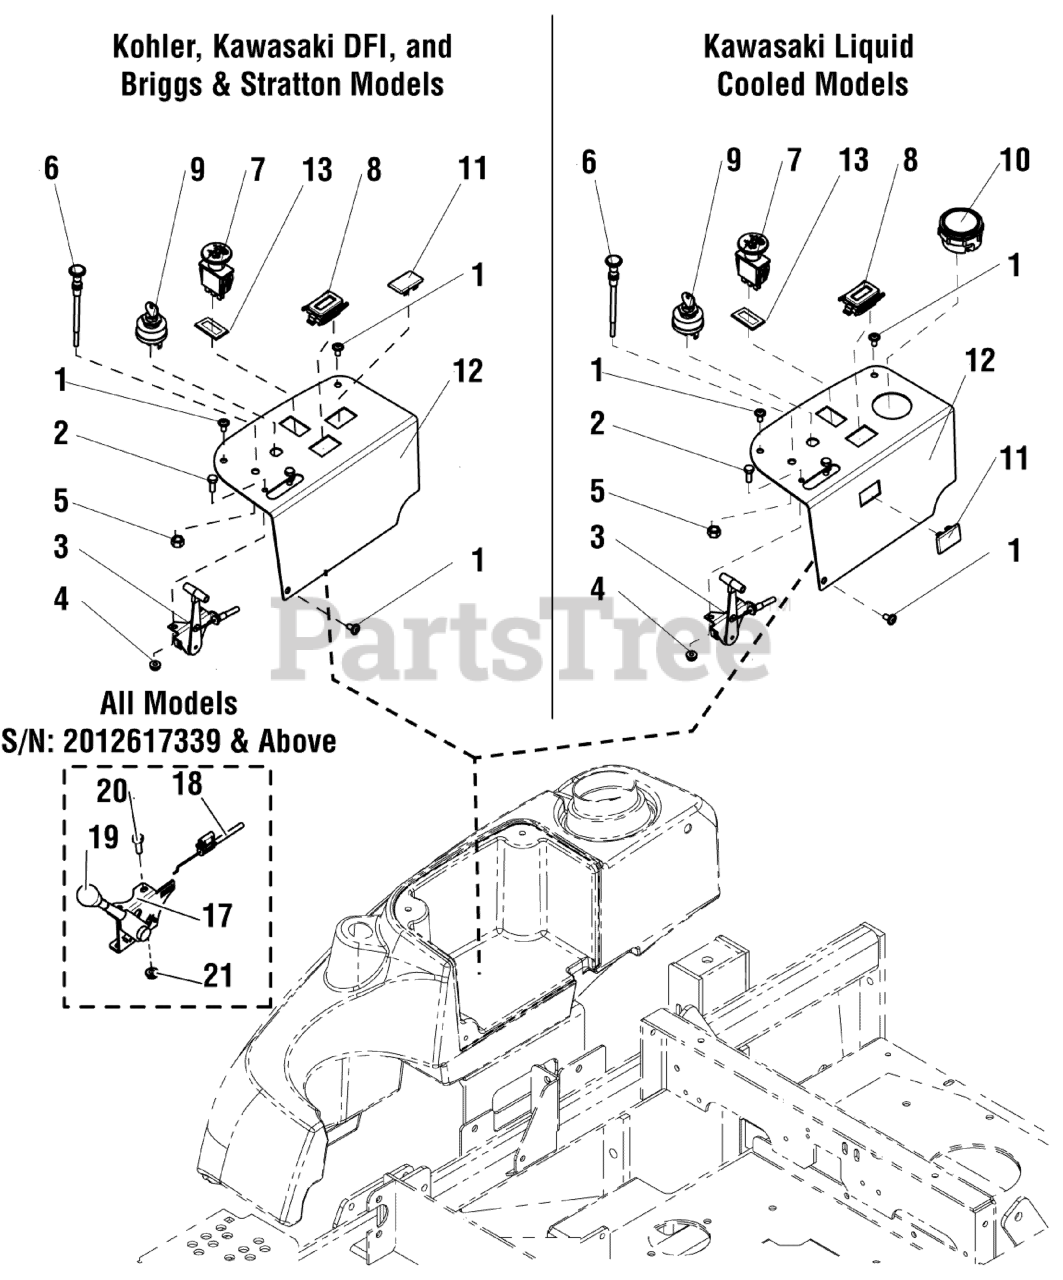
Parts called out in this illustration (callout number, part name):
1	SCREW, ALLEN HEAD, 1/4-20X1/2
2	BOLT, 1/4-20 X 3/4" GD5
3	CABLE, THROTTLE CONTROL, 54"
4	NUT, 1/4-20 HEX NYLOCK FLANGE
5	NUT, HEX 3/8-24
7	SWITCH, BLADE ENGAGEMENT
8	HOUR METER
9	SWITCH, IGNITION, 6 POST
10	GAUGE, WATER TEMPERATURE
11	HOLE, PLUG DASH
13	RING, SWITCH RETAINER
17	LEVER, THROTTLE CONTROL, HEAVY-DUTY
18	CABLE, THROTTLE, 52"
19	THROTTLE CONTROL HANDLE/KNOB
20	SCREW, #10-24 X 3/4"
21	NUT, #10-24 HEN NYLON LOCK
